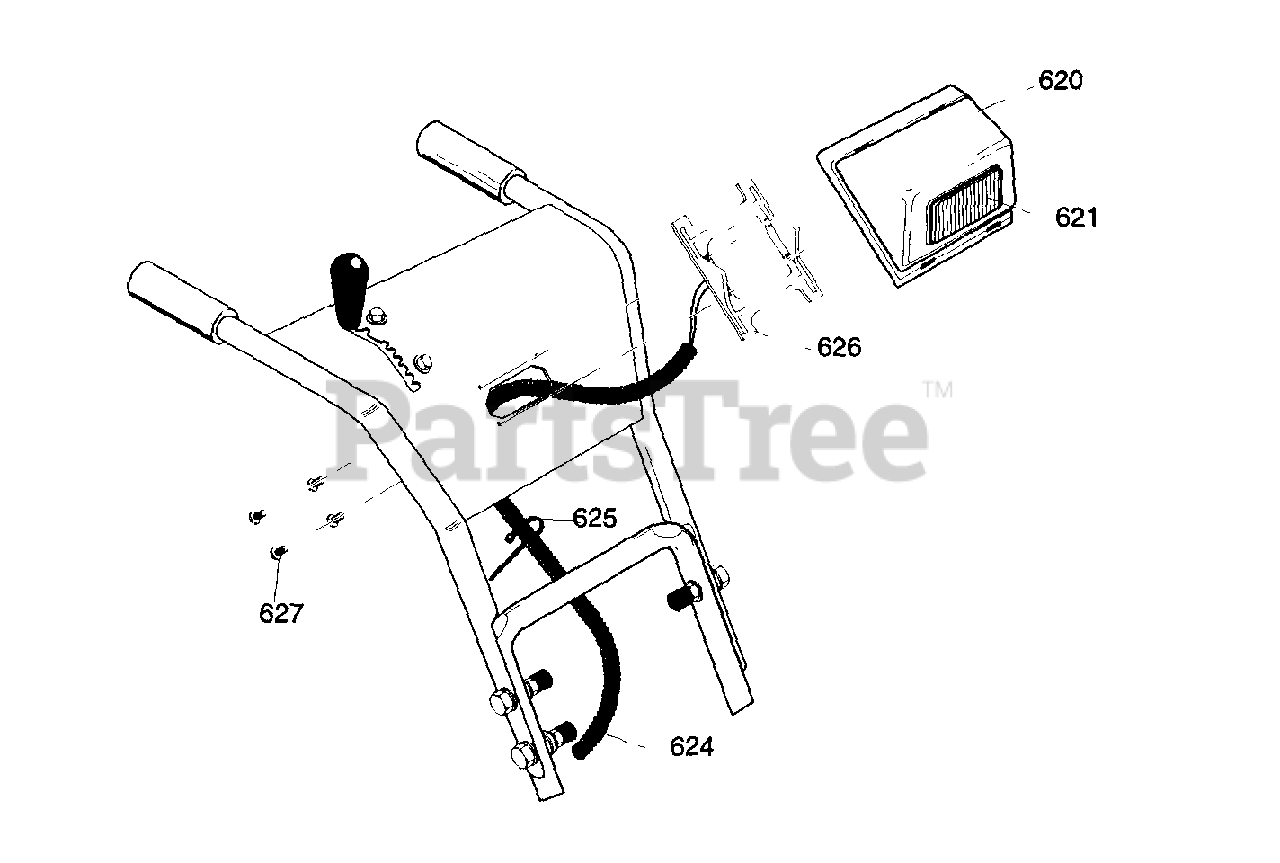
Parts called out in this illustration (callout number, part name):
620	HOUSING, LIGHT
621	HEADLIGHT, ASSY
624	WIRE HARNESS, HDLIGHT
625	TIE, CABLE
626	BRACKET, LIGHT PANEL
627	SCREW, #8 X 75
